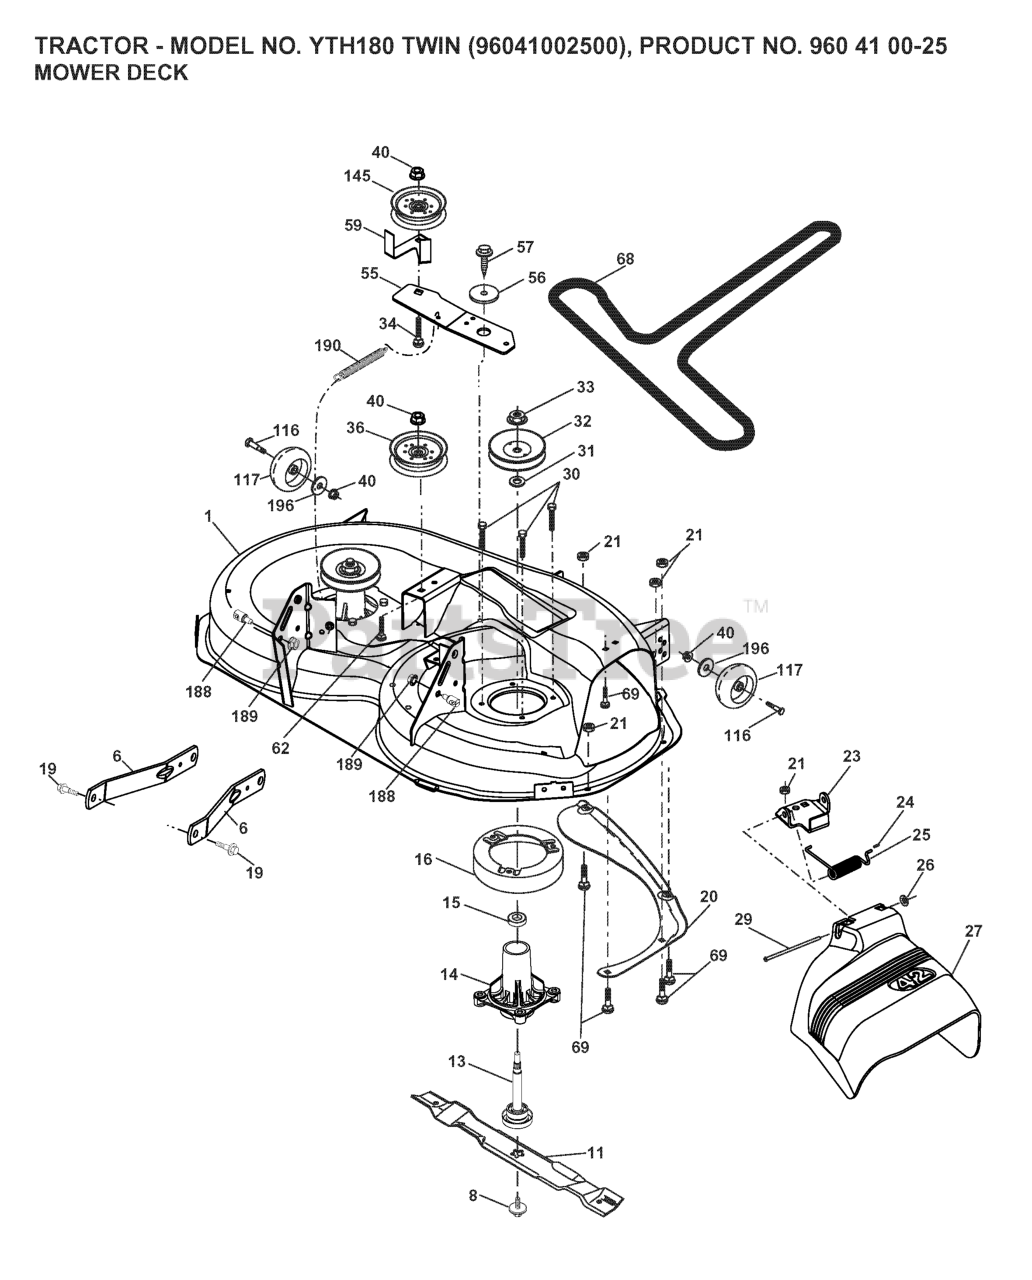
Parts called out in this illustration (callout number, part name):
1	DECK.WELDMENT.42"
6	ARM.SUSPENSION.MOWER.R
8	BOLT.WASHER.ASM.7/16-2
11	42" HI-LIFT BLADE
13	SHAFT.ASM.MDRL.N/GREASE.38
14	RP.HOUSING.MANDREL.4PT.
16	STRIPPER.MANDREL.ROUND.BLACK
19	BOLT.SHOULDER
20	BAFFLE.VORTEX
21	LOCKNUT
23	BRKT.DEFLECTOR.38"2005+
24	CAP-SLEEVE LT
25	SPRING.TORSION.DEFLECT
26	NUT PUSH M
27	SHIELD.DEFLECTOR.MOWER.42"BLAC
29	ROD.HINGE
30	SCREW, WASHER HEAD
31	WASHER.SPACER.MANDREL
32	PULLEY/MANDREL
33	NUT.FLANGE.LOCK.TOP
34	BOLT.3/8-16X1.50
36	PULLEY.IDLER.2006
40	NUT LOCK FLG 3/8-16 UNC
55	IDLER.ARM
56	SPACER.RETAINER
57	SCREW 3/8-16X1
59	GUARD, BELT
62	BOLT
68	BELT V SECONDARY
69	BOLT
116	BOLT M
117	WHEEL.GAGE.HALF.SPOKED
118	LOCKNUT
145	PULLEY.IDLER.48"PRIMARY
188	STUD.FASTNER.W/ANTI-ROTATE
189	NUT LOCK HEX FLANGE 5/16-18
190	SPRING.MOWER.DRIVE.ELECTRIC
196	WASHER.5/16.FLAT.STE.STD.
